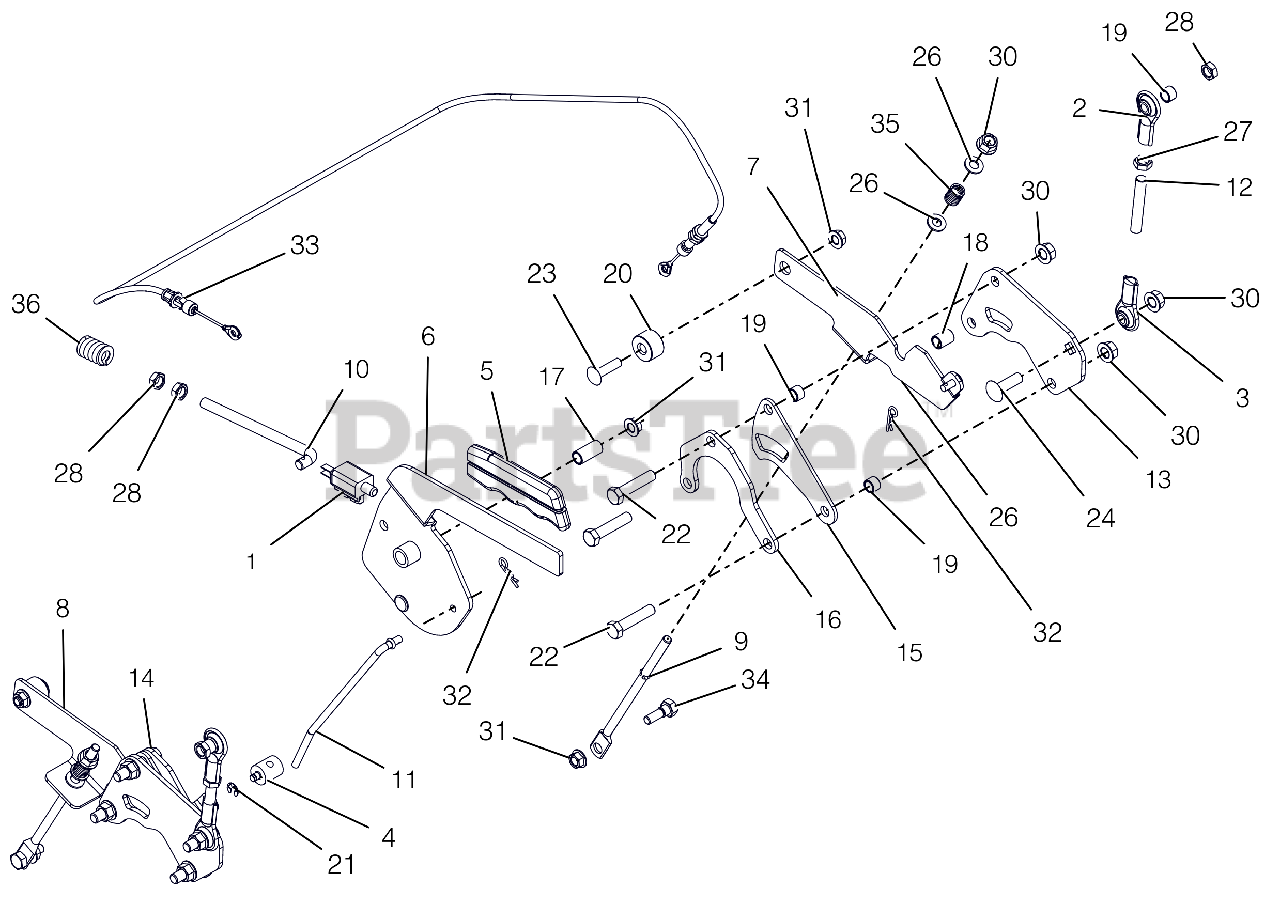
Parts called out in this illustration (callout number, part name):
1	SWITCH, SINGLE POLE N.O.
2	ROD END, .38 RH
3	END, ROD-.38 LH
4	TRUNION, 1/4-20
5	GRIP, PARKING BRAKE (YELLOW)
6	LEVER, PARKING BRAKE
7	ARM, BRAKE - LH (W/PIN)
8	ARM, BRAKE-RH
9	ROD, LINK - TRANSMISSION BRAKE
10	ROD, OVER CENTER
11	ROD, BRAKE LINK
12	ROD, STEERING LINK
13	BRKT, TRANSAXLE STEERING
14	BRKT, SPACER
15	BRKT-SPACER
16	PLATE, REAR REINFORCING
17	BSHG-SLV .385X.500X1.045
18	SPCR, SLV .385X.500X.652
19	SPCR, SLV .385X.500X.350
20	SPCR, FLANGE
21	RG-RTNG-EXT .250X.025
22	@BLT-HEX .38-16X1.75 GR5 YWZC
23	@BLT-RHDSHSQNK.31-18X1.25 G5YZ
24	@BLT-RHDSSQNK .38-16X1.25 G5YZ
26	@WSHR-FL-STL.344X.688X.065YWZC
27	NUT-JAM .375-24 YWZC
28	NUT-HEX-JAM .375-16 YWZC
30	@NUT-LK-TOP-FLG .38-16 YWZC
31	@NUT-LK-TOP-FLG .31-18 YWZC
32	PIN-HAIR INT .08X.18X1.18 YWZC
33	CABLE, BRAKE
34	BOLT,SHLDR .38X.25 -.31-18X.75
35	SPRING, COMPRESSION
36	SG-COMP .187X.56X1.62
